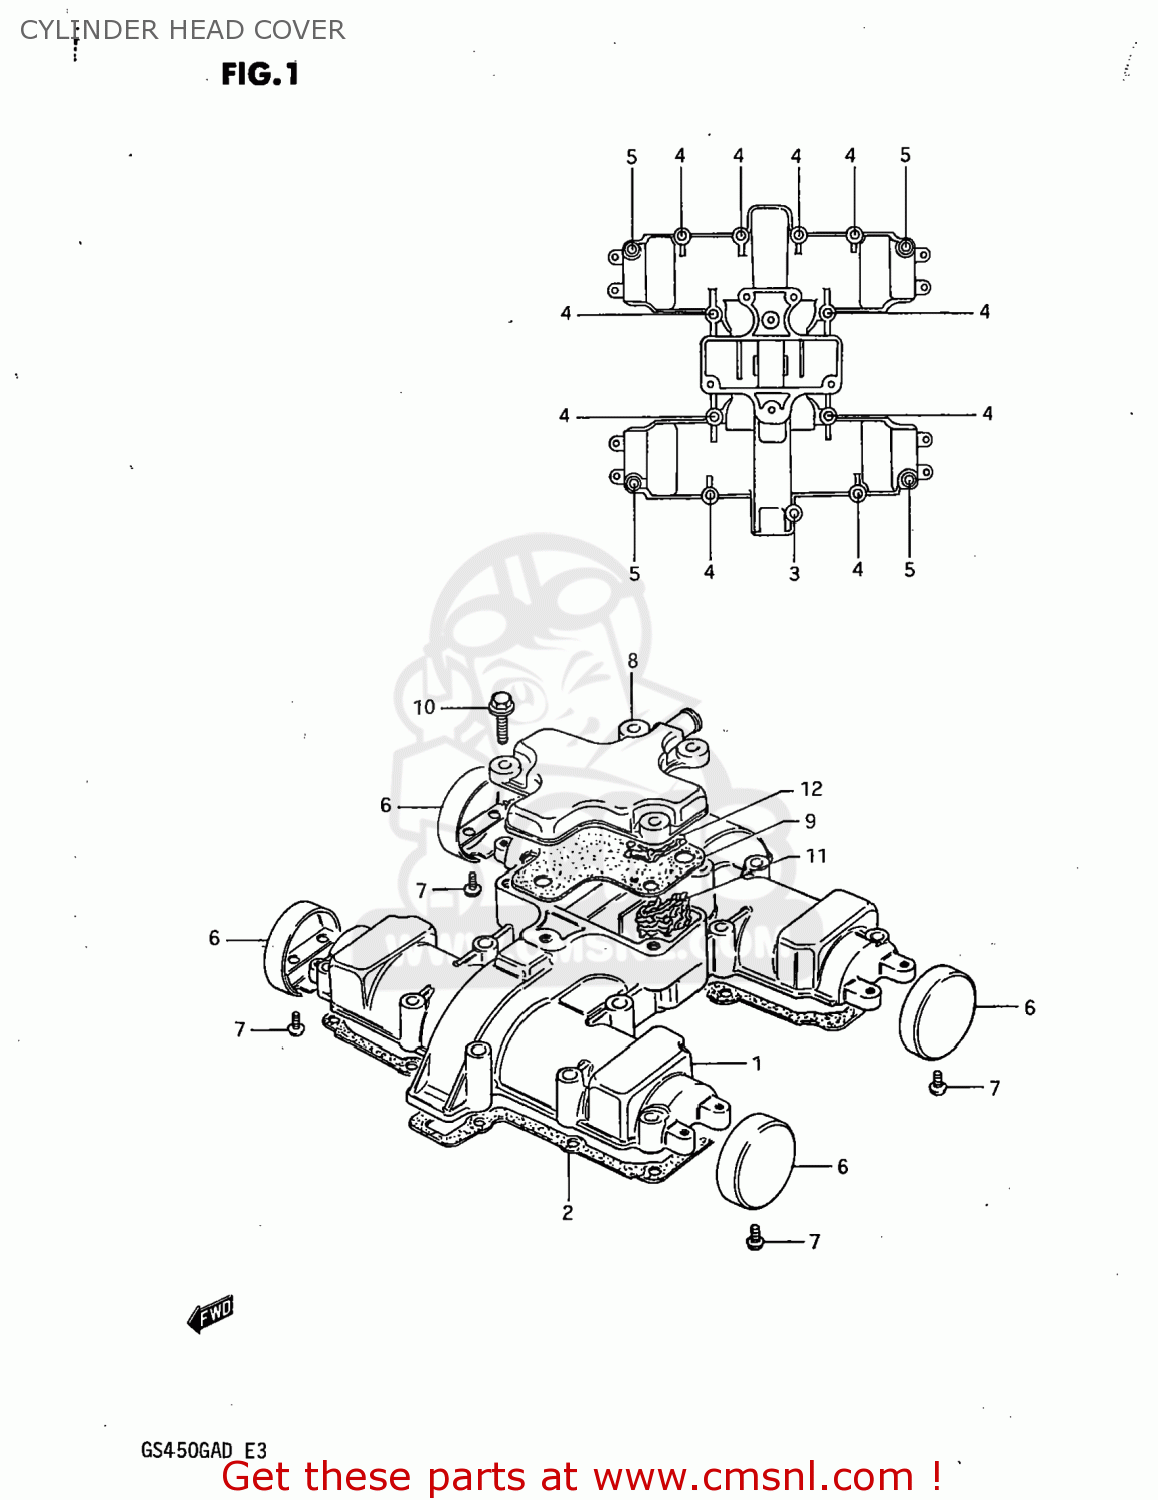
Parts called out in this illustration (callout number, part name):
1	COVER,CYLINDER HEAD
2	GASKET,CYLINDER HEAD COVER (MCA)
3	BOLT,UNDER
4	BOLT
5	BOLT
6	CAP,CYLINDER HEAD COVER
7	SCREW
8	COVER,BREATHER
9	GASKET (MCA)
10	BOLT,REAR
11	COVER,BREATHER
12	SEPARATOR,OIL BREATHER
